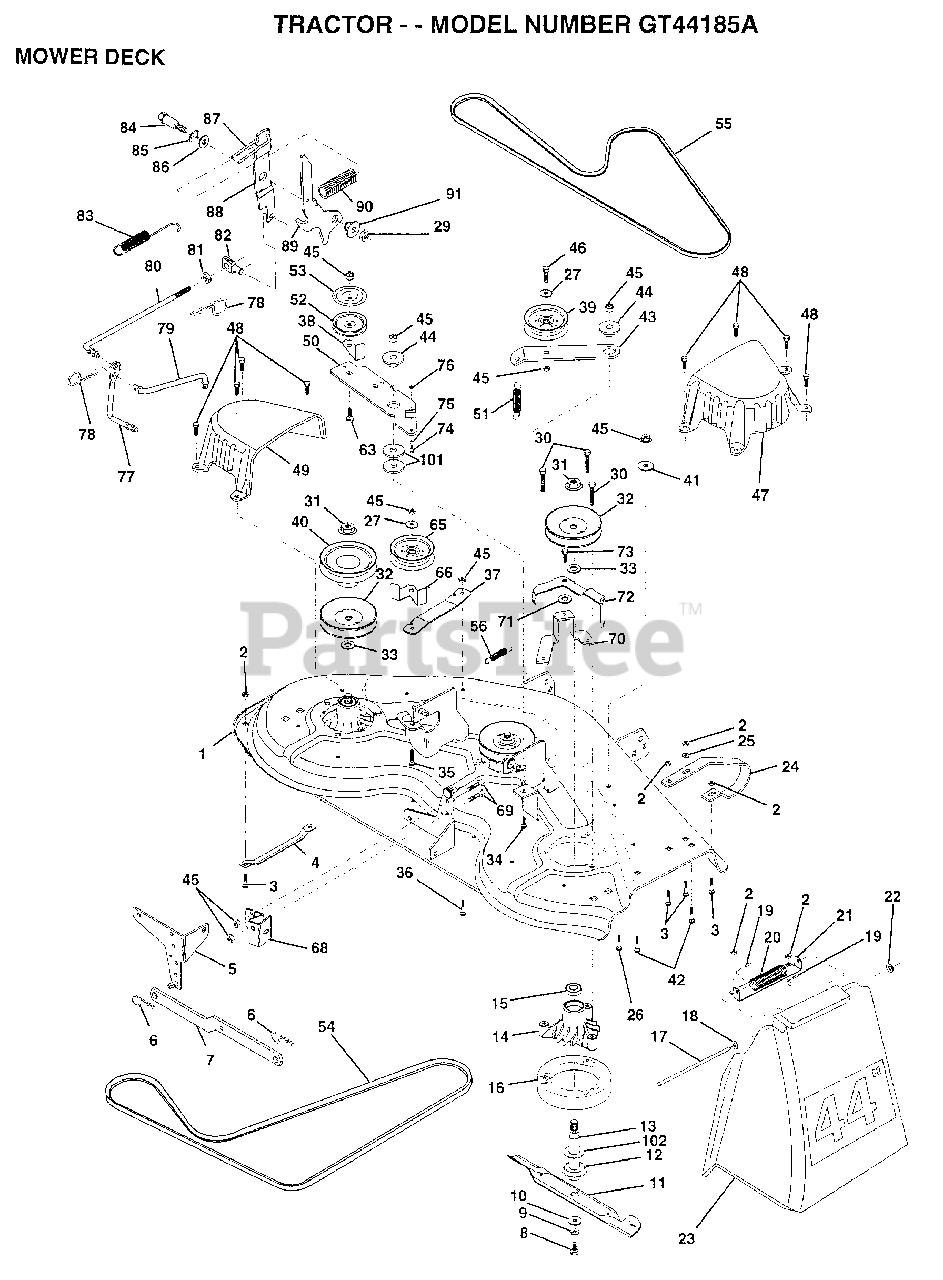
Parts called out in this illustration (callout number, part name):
1	"DECK ASM WELD44"""
4	RUNNER-LH M
5	BRKT.ASM.SW.44/50
8	BLADE BOLT
10	WASHER.HARD.BLADE
11	"BLADE.44"" HIPERF"
12	BEARING.BALL
13	SHAFT.ASM.W/BRNG
14	HOUSING.MAND.44.V
15	BEARING
16	STRIPPER RND MWR
17	ROD-HINGE T
18	WASHER
19	CAP-SLEEVE LT
20	SPRING TORSION
21	BRKT DEFLECTOR
22	NUT PUSH M
23	DEFLECTOR SHIELD
24	RUNNER.RH
25	WASHER M
26	BOLT
27	WASHER
32	PULLEY.MANDREL.42
33	WASHER
34	BOLT.3/8-14X1.25
35	BOLT
36	BOLT D
37	STIFFENER.ARM.IDL
38	KEEPER BELT IDLER
39	FLAT IDLER PULLEY
40	"PULLEY.DRIVEN.44"""
42	BOLT
43	"ARM.IDLER.SEC.44"""
44	SPACER RETAINER
47	"COVER.MAND.RH.44"""
48	SCREW.1/4-20X5/8
49	COVER.MANDREL.LH
50	ARM.IDLER.PRIMARY
51	"SPRING.SEC.44""VEN"
52	PULLEY.IDLER.VGRO
53	SHIELD.IDLER.44.V
54	BELT-V MOWER PRIM
55	BELT-V.88.12.MW
56	"SPRING,EXTENTION"
57	BAR.ASM.GUAGE.WHL
58	WHEEL.GAGE.BLK.PL
59	BOLT M
60	PIN.CLEVIS
61	BRACKET.GUAGE.WHL
63	BOLT.3/8-16X1.50
64	WASHER
65	PULLEY IDELR FLAT
67	LOCKNUT
68	BRACKET PVT MCH
70	"BRACKET SUPT 44"""
71	HARD SMALL WASHER
72	ARM BRAKE ASM
73	BOLT.SHLD.5/16-18
75	SHOULDER BOLT
76	LOCKNUT
77	PIVOT ROD
78	RETAINER M
79	ROD CLUTCH SECON
80	ROD.CLUTCH.PRIM44
81	NUT
82	TRUNION ADJ
83	SPRING.EXT.RETURN
84	SHOULDER BOLT
85	RING
86	WASHER
87	SPRING KEEPER
88	CLUTCH ARM SECOND
91	BUSHING
93	WASHER
101	"WASHER, WEAR LT"
102	WASHER.FELT.
